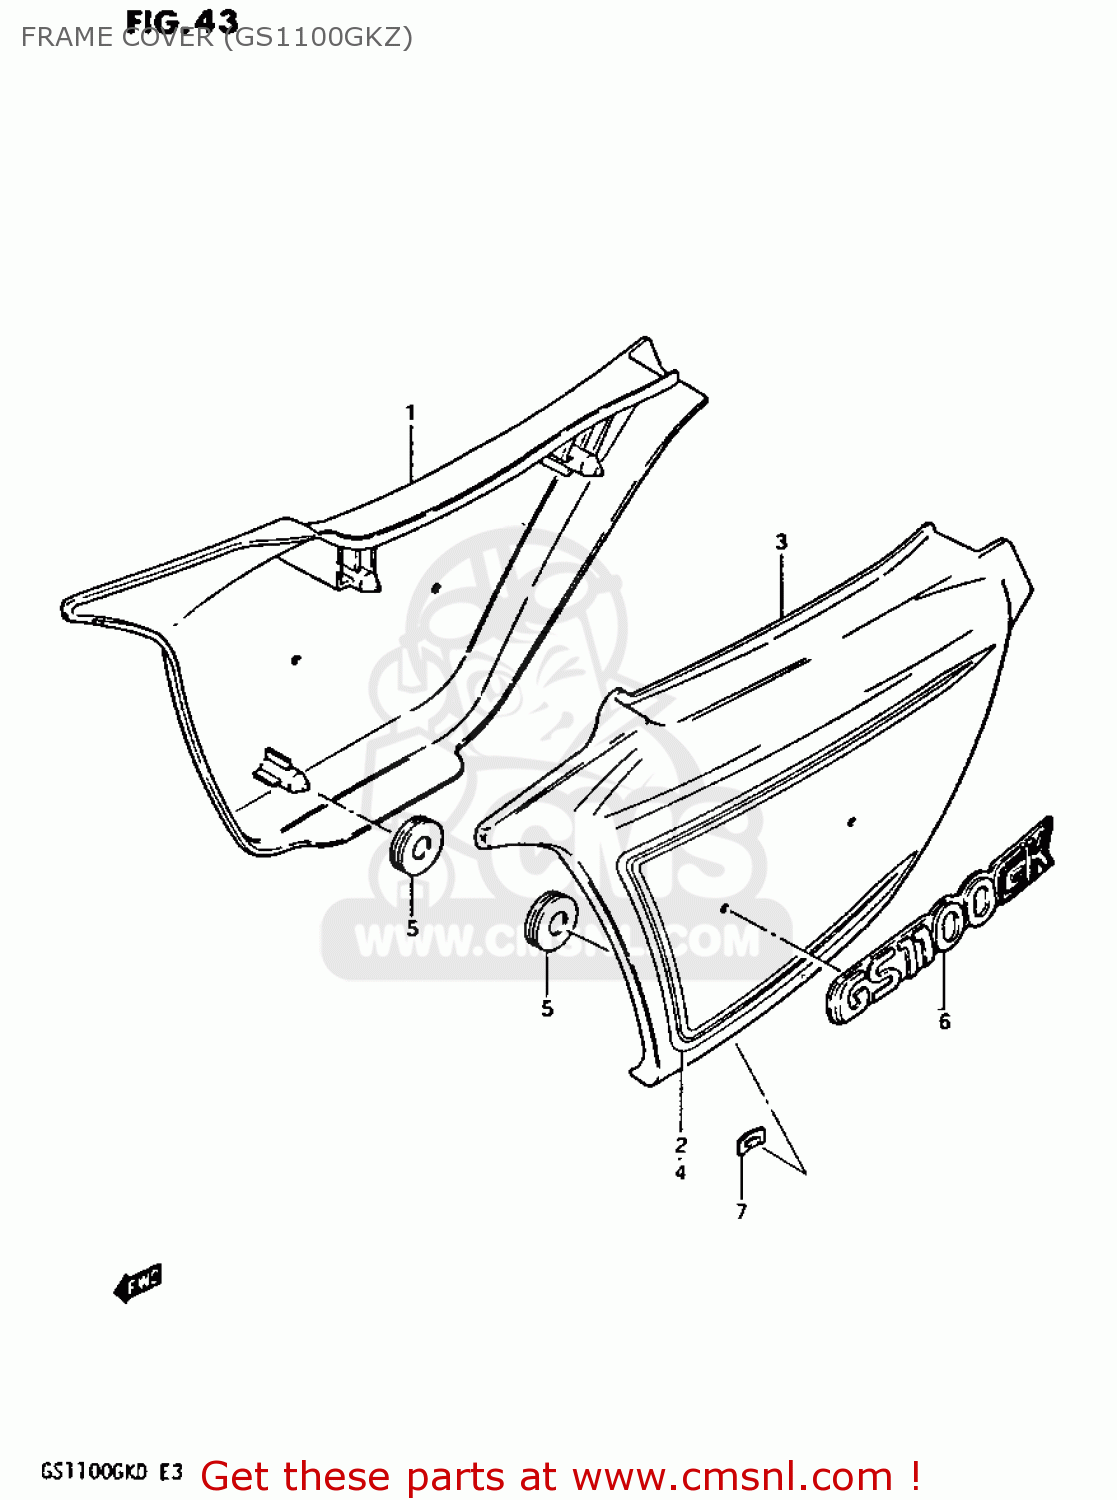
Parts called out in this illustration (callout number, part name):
1	COVER,FRAME,R
2	TAPE SET,FRAME COVER
3	COVER,FRAME,LH (RED)
4	TAPE SET,FRAME COVER
5	CUSHION
6	EMBLEM,FRAME COVER
7	NUT
